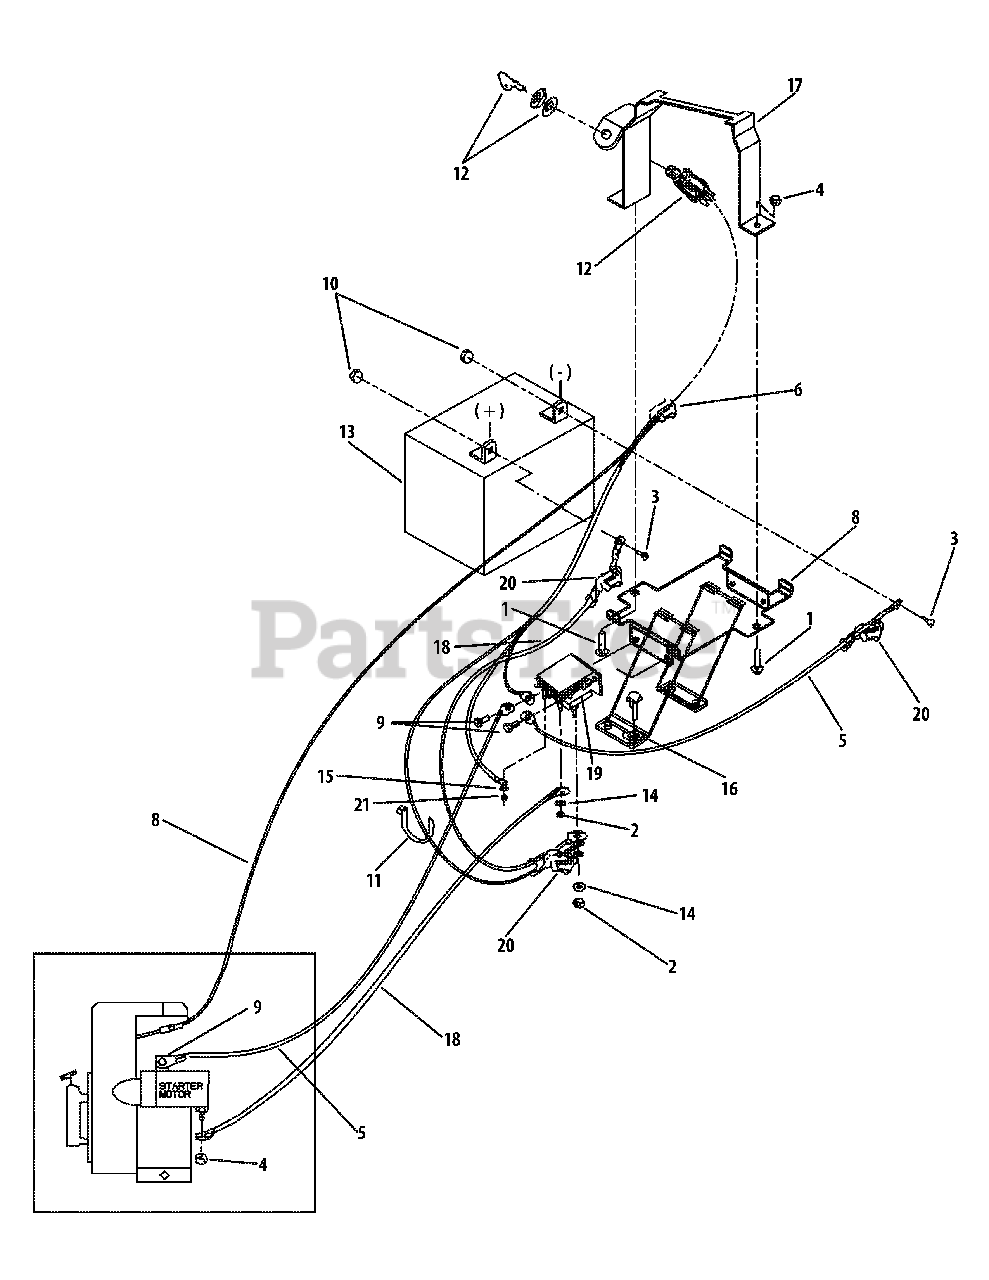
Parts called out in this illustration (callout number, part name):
1	Carriage Screw 1/4-20 x 1.25
2	Hex Nut 5/16-24
3	Flange Screw 1/4-20 x .625
4	Hex Locknut1/4-20
5	Cable (Ground Wire)
6	Wire Harness Assembly
7	Electric Start Harness
10	Hex Nut 1/4-20
11	Cable Tie
12	Ignition Switch
13	Battery 270 CCA
14	Lock Washer 5/16
15	Lock Washer #10
16	External Lock Washer 5/16
17	Keyswitch Clamp
18	Cable (Solenoid to Starter Motor)
19	Solenoid
20	Insulating Boot
